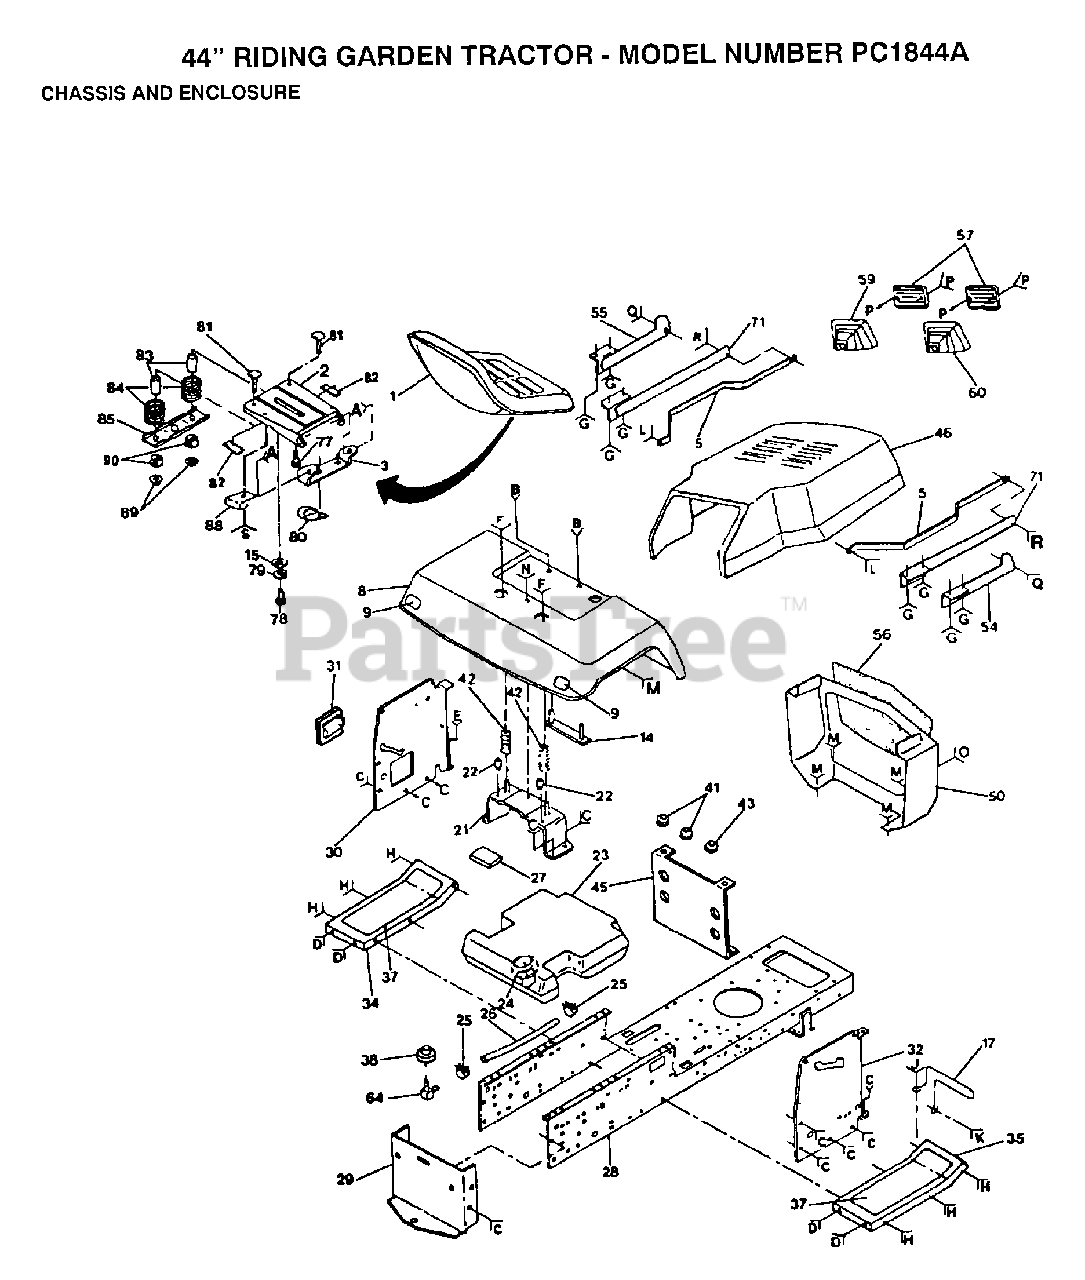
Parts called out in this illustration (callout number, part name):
9	REFLECTOR-TAIL YT
11	SCREW
12	WASHER
15	WASHER
17	GUARD MUFFLER HYT
18	NUT
20	WASHER
22	NUT-PUSH YT
25	HOSE CLAMP
27	PAD-SPACER LT
28	CHASSIS
29	DRAWBAR LT/YT
31	COVER ACCESS
32	PANEL DASH RH YT
33	BOLT LT
36	BOLT
37	"PAD,FOOTREST"
38	BUSHING OUTLET T
39	LOCKWASHER
41	SNAP BUSHING T
42	SPRING COMPRESSIO
49	SCREW LT
54	STRAP ASSY T
55	STRAP ASSY T
56	SCREEN GRILL GTV
63	BOLT
64	FUEL TANK STEM GT
66	SCREW GTV
67	WASHER HYT
68	WASHER
69	SCREW
71	STRAP ASSY-REAR T
73	BOLT T
75	"BOLT,SHOULDER"
77	"BOLT,SHOULDER"
78	BOLT
79	LOCKWASHER
80	CLIP T
81	BOLT
82	STRIP FORM
83	SPACER SPLIT
84	SPRING COMPRESSED
85	BRKT SWITCH
87	"NUT,KEPS"
90	BUSHING
